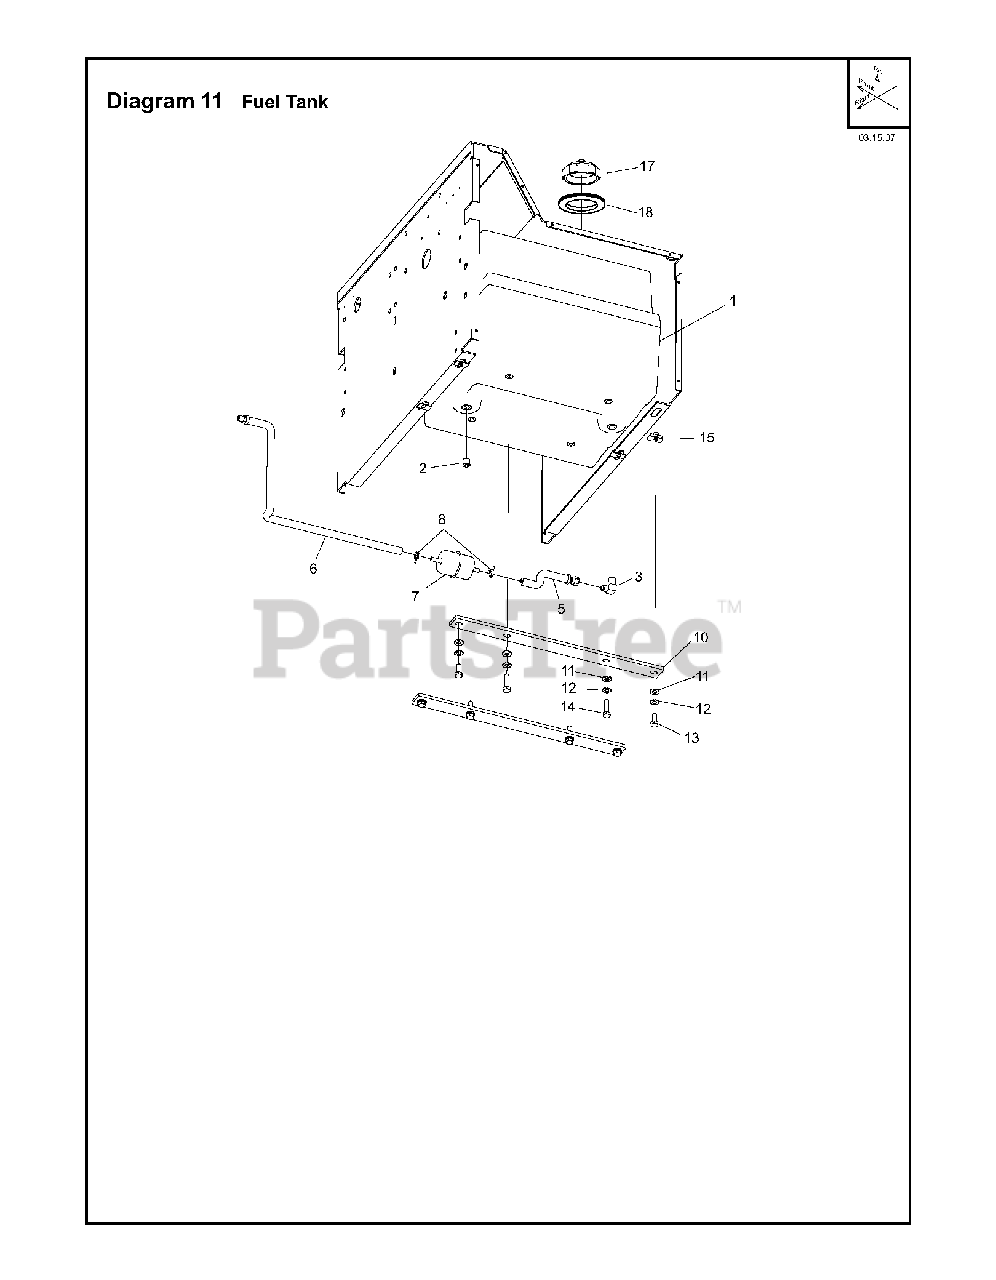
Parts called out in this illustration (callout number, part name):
1	FUEL TANK PLASTIC. 2 PORTS
2	PLUG
3	FTTNG. ELBOW 90 .25NPTx.25 SAE
5	HOSE ASSY
6	HOSE ASSY
7	FILTER. GASOLINE. INLINE 1/4
10	FUEL TANK MOUNTING BAR. PAINTD
11	WASHER
12	LOCKWASHER. STAR EXTERNAL M-8
13	HHCS. M8 x 1.25 x 20 DIN933 ZP
15	U-NUT.M8 x 1.25 (.8-4 mm MATL)
17	GAS CAP w/o GAUGE
